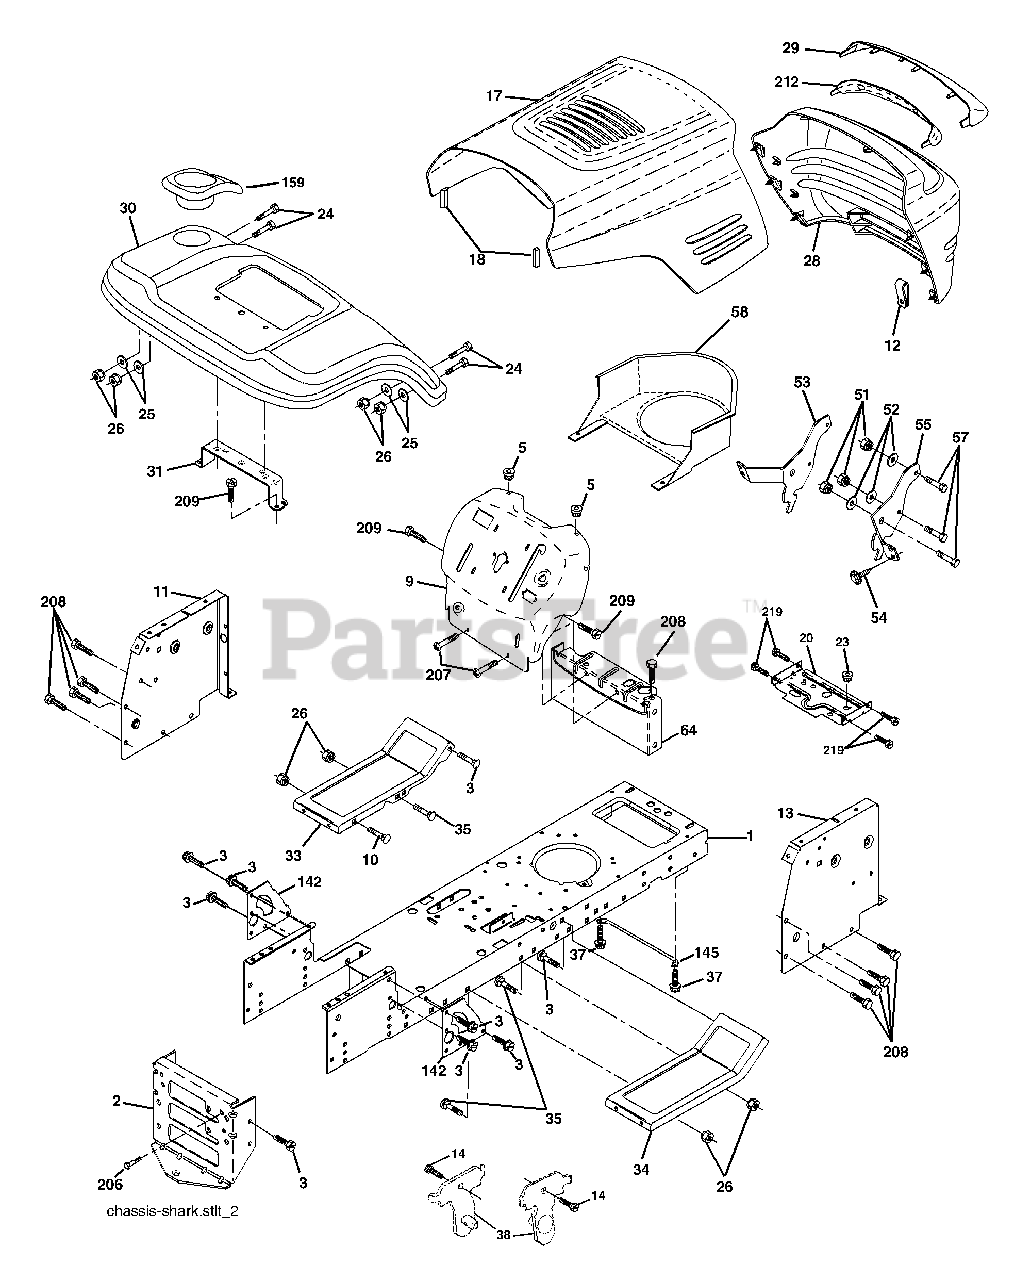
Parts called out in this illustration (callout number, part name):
1	Chassis
2	Drawbar
3	Screw 3/8-16 x .75
5	Bumper Hood/Dash
9	Dash P/L
10	Bolt Carriage 3/8-16 x 1
11	Panel Dash Lh
12	Clip Tinnerman
13	Panel Dash Rh
14	Screw Thdrol 3/8-16 x 1-1/4
17	Hood W/Side Louvers
18	Bumper Hood Large
20	Plate Mtg Battery Fuel Tank
23	Bushing
24	Bolt Fin Hex 3/8-16 x 1 Gr 5
25	Washer 13/32 x 13/16 x 12 Ga
26	Nut Lock Hex W/Ins 3/8-16 Unc
29	Lens
30	Fender Footrest STLT Pnt
31	Bracket Support Fender
33	Footrest Pnt Lh
34	Footrest Pnt Rh
35	Bolt Rdhd Sht Sqnk 3/8-16 x 3/4
37	Screw Thdrol 6/16-18 x 1/2 TYT
38	Bracket Asm. Pivot Mower Rear
51	Nut Lock Hex W/Ins 1/4-20
52	Washer 9/32 x 7/8 x 16 Ga.
53	Bracket Grille Lh
54	Screw Hex Wshd 8-18 x 7/8
55	Bracket Grille Rh
57	Bolt Hex 1/4-20 x 3/4
58	Duct Air
64	Dash Lower STLT
142	Plate Reinforcement STLT
145	Rod Pivot Chassis/Hood
159	Cupholder
206	Bolt Shoulder 5/16-18
207	Screw Thdrol 5/16-18 x 1/2
208	Screw Thdrol 3/8-16 x 1/2
209	Screw Hexwsh Thdr 3/8-16 x 3/4
212	Insert Lens Reflect
219	Screw 5/16-18 x 3/4
